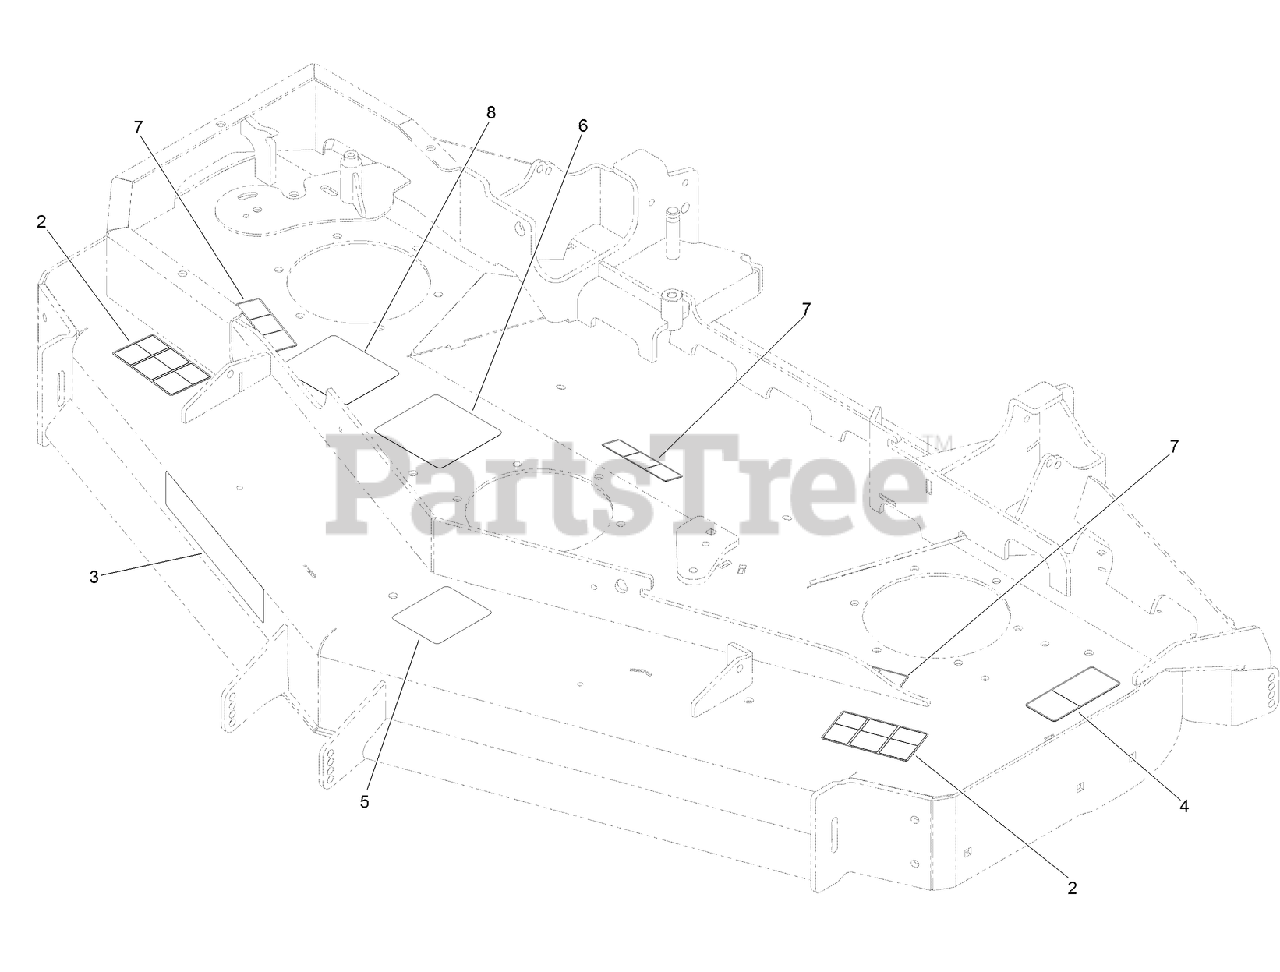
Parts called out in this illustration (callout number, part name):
2	DECAL-DANGER
4	DECAL-TORQUE, BLADE BOLT
5	DECAL-ROLLER, ANTI-SCALP
6	DECAL-ROUTING, DECK BELT
7	DECAL-MISSING, COVER
8	DECAL-SPINDLE, COUNTER ROTATING
